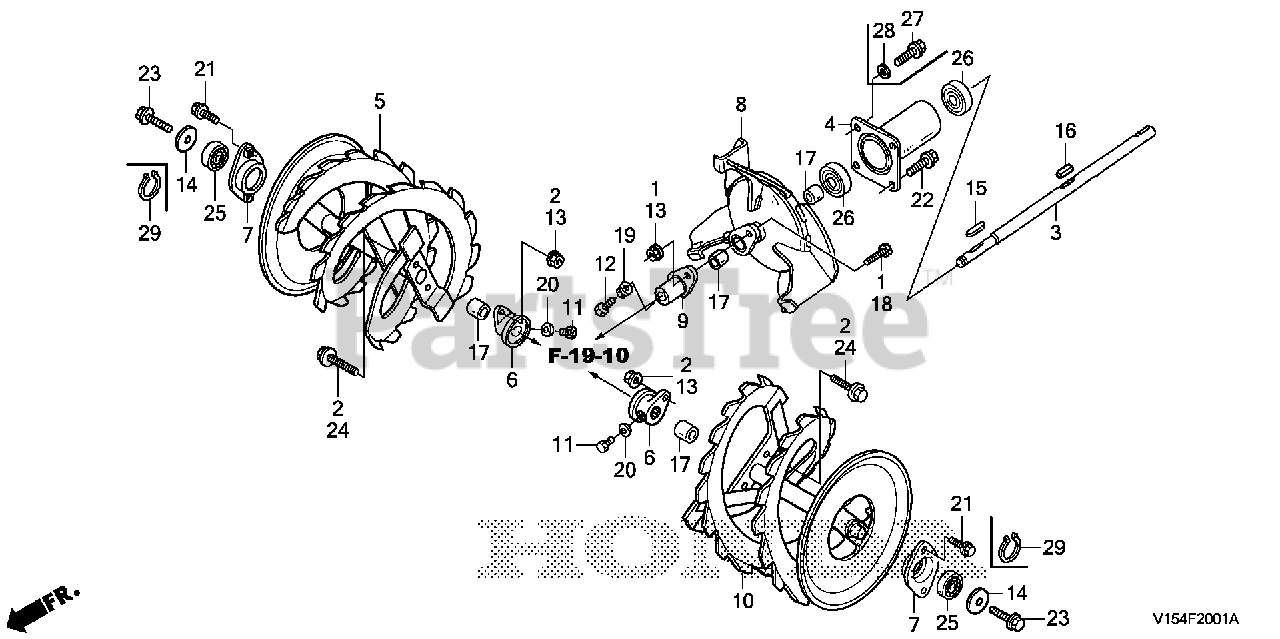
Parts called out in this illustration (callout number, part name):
1	BOLT SET, BLOWER
2	BOLT SET, AUGER
3	SHAFT, AUGER DRIVE
4	HOLDER, BEARING
5	AUGER, R. (COO)
6	FLANGE, AUGER SHEAR
7	HOLDER, AUGER BEARING
9	PIPE, JOINT
10	AUGER, L. (COO)
11	BOLT, SPECIAL (10X16)
12	BOLT, SPECIAL (8X25)
13	NUT, SELF-LOCK (8MM) (CLINCH)
15	KEY (6X6X40)
16	KEY (7X7X33)
17	BUSH (25X28X25)
18	BOLT, HEX. (8X25)
19	NUT, FLANGE (8MM)
20	WASHER, SPRING (10MM)
21	BOLT, FLANGE (8X12)
24	BOLT, FLANGE (8X25)
25	BEARING, RADIAL BALL (6004UU)
26	BEARING, RADIAL BALL (6205UU)
27	BOLT, FLANGE (8X20)
28	WASHER, PLAIN (8MM)
29	CIRCLIP, OUTER (20MM)
